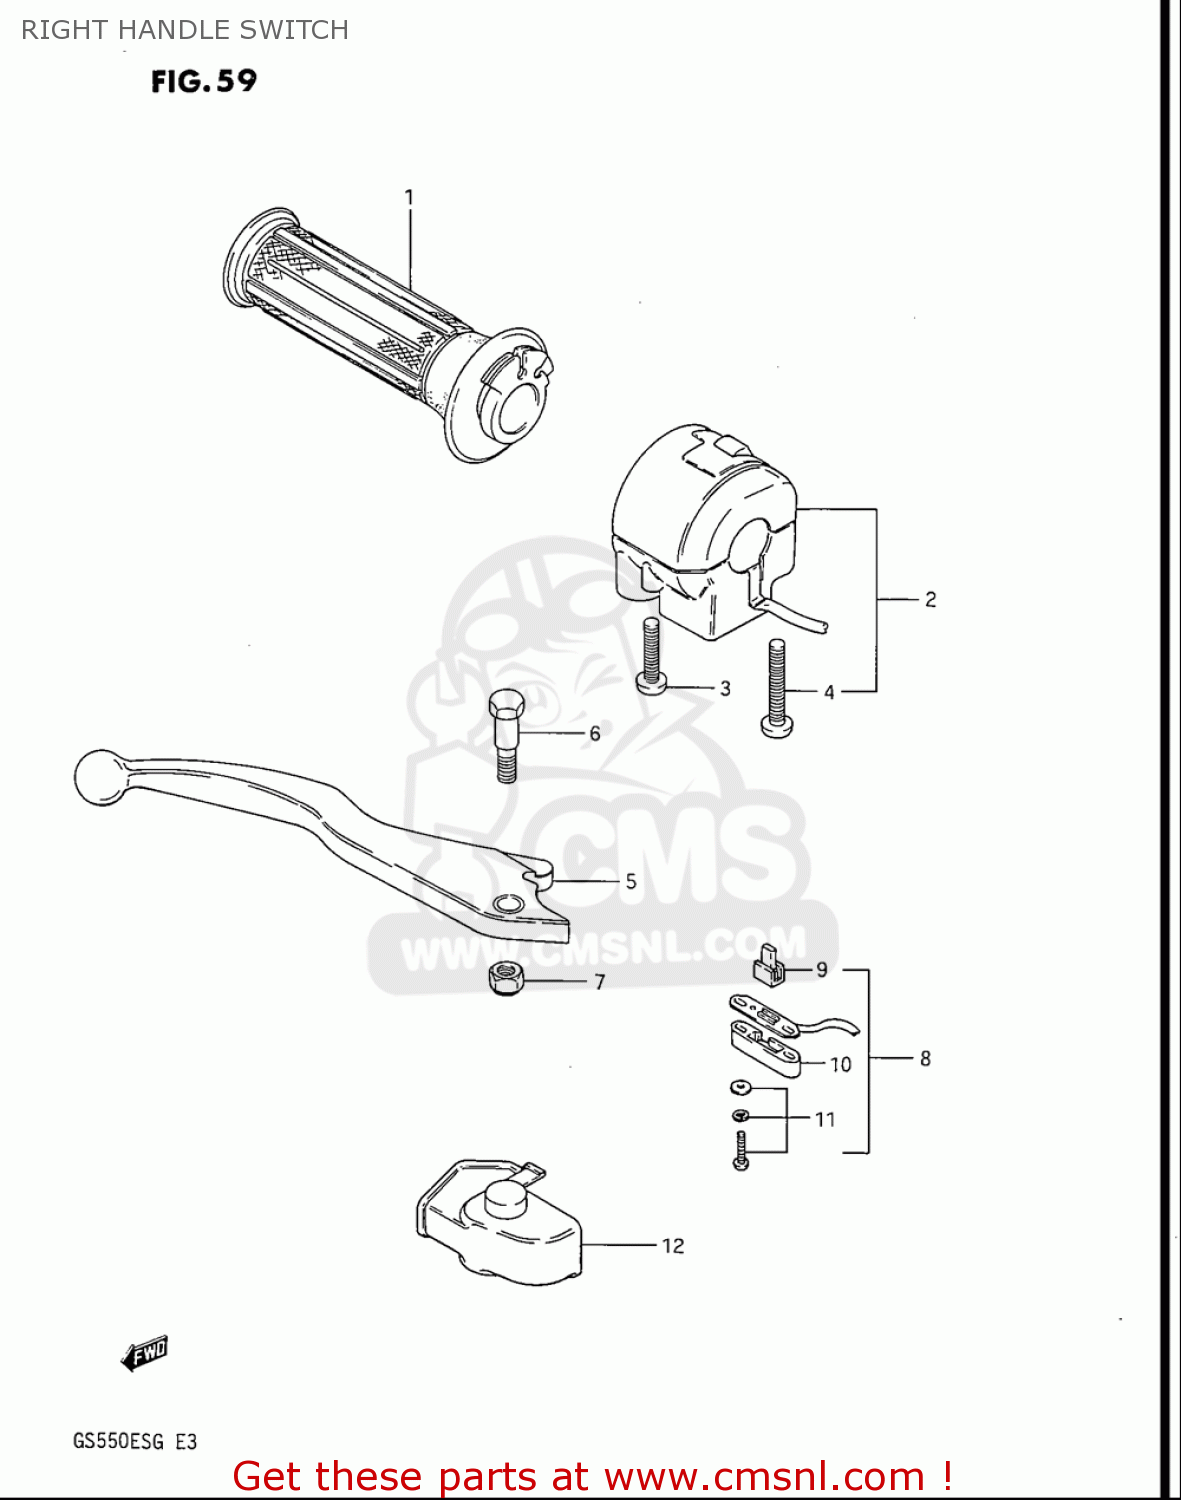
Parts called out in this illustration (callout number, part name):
1	GRIP,THROTTLE
2	SWITCH ASSY,HANDLE
3	SCREW(5X25)
4	SCREW
5	LEVER,BRAKE
6	BOLT,LEVER PIVOT
7	NUT
8	SWITCH ASSY,STOP
9	CONTACT,SWITCH
10	COVER,FR BK TERMINAL BASE
11	SCREW
12	COVER,BRAKE LEVER
